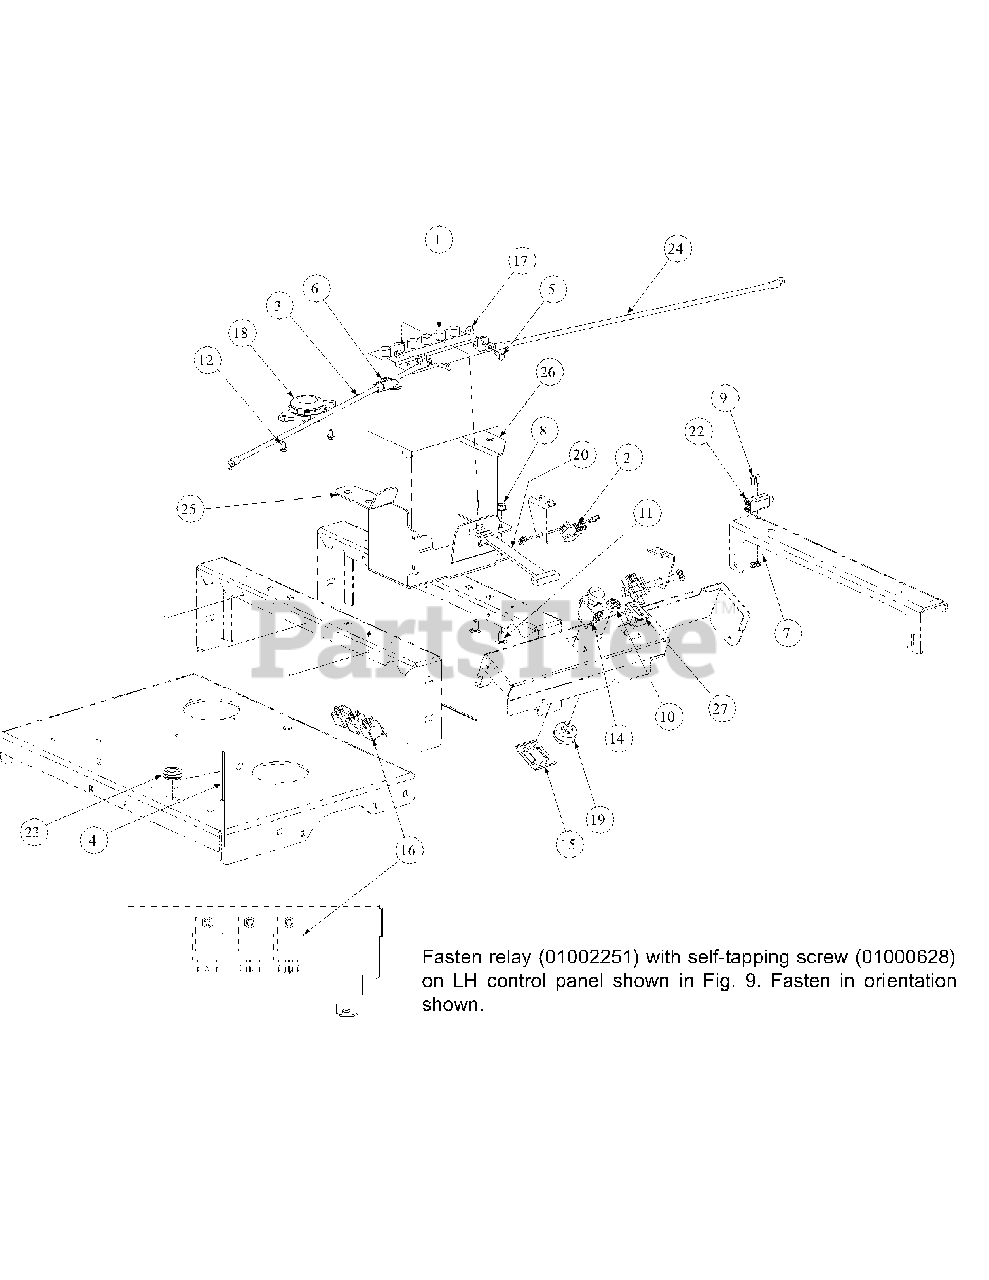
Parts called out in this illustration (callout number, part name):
2	Switch, Safety
3	Cable, Battery, Red, 36"
4	Tie, Cable, 3/16 x .05 x 7.4"
5	Screw, Hex, Cap, 1/4-20 x .75
6	Boot, 1" OD Rubber Battery-PST, Red
7	Nut, Lock, Nylon Insert, #10-32
8	Nut, Hex, Flange Lock, 3/8-16
9	Screw, Phillips Head, Machine, 10-32 x 5/8
10	Nut, W/Cap, 5/8-32 Ignition
11	Carriage Bolt, 3/8-16 x .75 LG.
12	Screw, TT, 1/4-20 x .500, Hex Index Washer
14	Switch, Electric, PTO
15	Bracket, PTO Switch Retainer
16	Relay, 12V 40A
17	Nut, 1/4-20, Hex Flange Lock Nut
18	Switch, Seat
19	Switch, Ignition, 6 Pin
19	Key, Ignition
20	Strap, Battery
22	Switch, Plunger
23	Grommet, .75 ID
24	Cable, Battery Black, 24"
25	Mount Bracket, Battery
26	Mount Bracket, Battery
27	Meter, Hour
